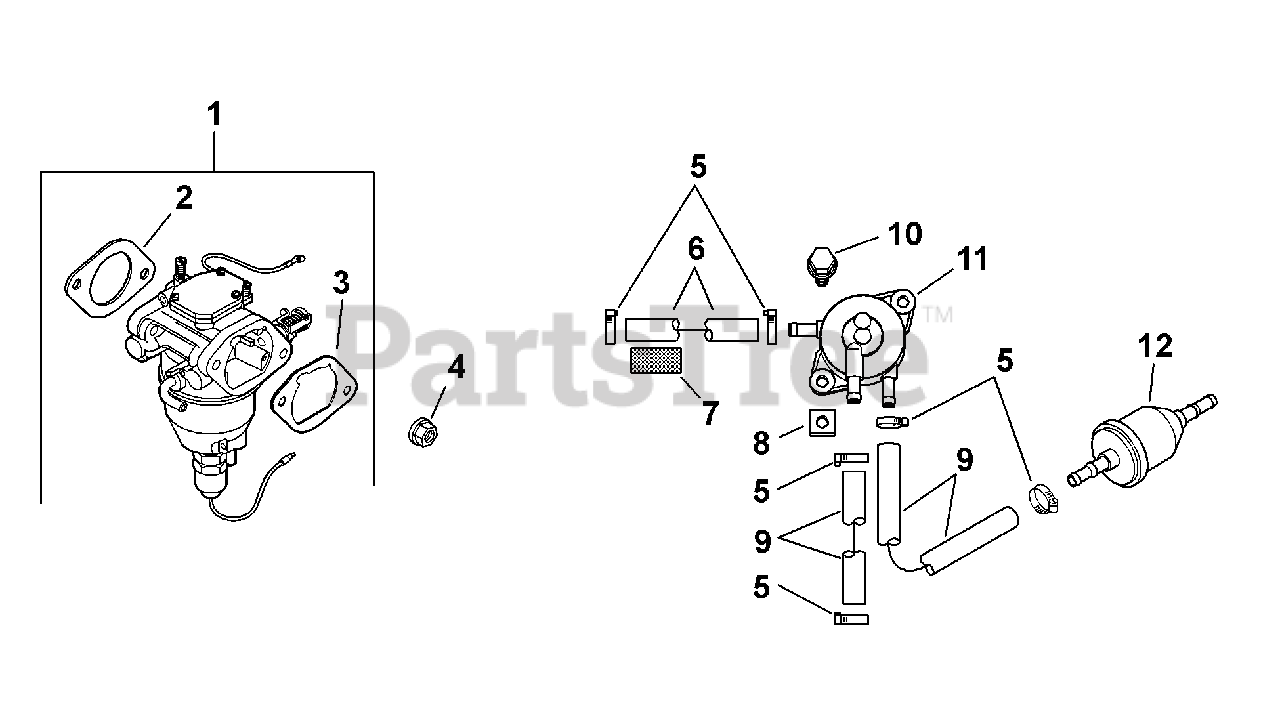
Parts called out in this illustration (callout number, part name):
1	Kit, Carburetor W/Gaskets (Includes 2,3)
2	Gasket, Carburetor
3	Gasket, Air Cleaner Base
4	Nut, Flg M6x1.0
6	Line, Flex 11" Pump-Pulse (Air Only)
7	Sleeve, Insulating 14"
9	Line, Fuel (24"-Cut To Length)
10	Screw, Tap M6x1.7x18
